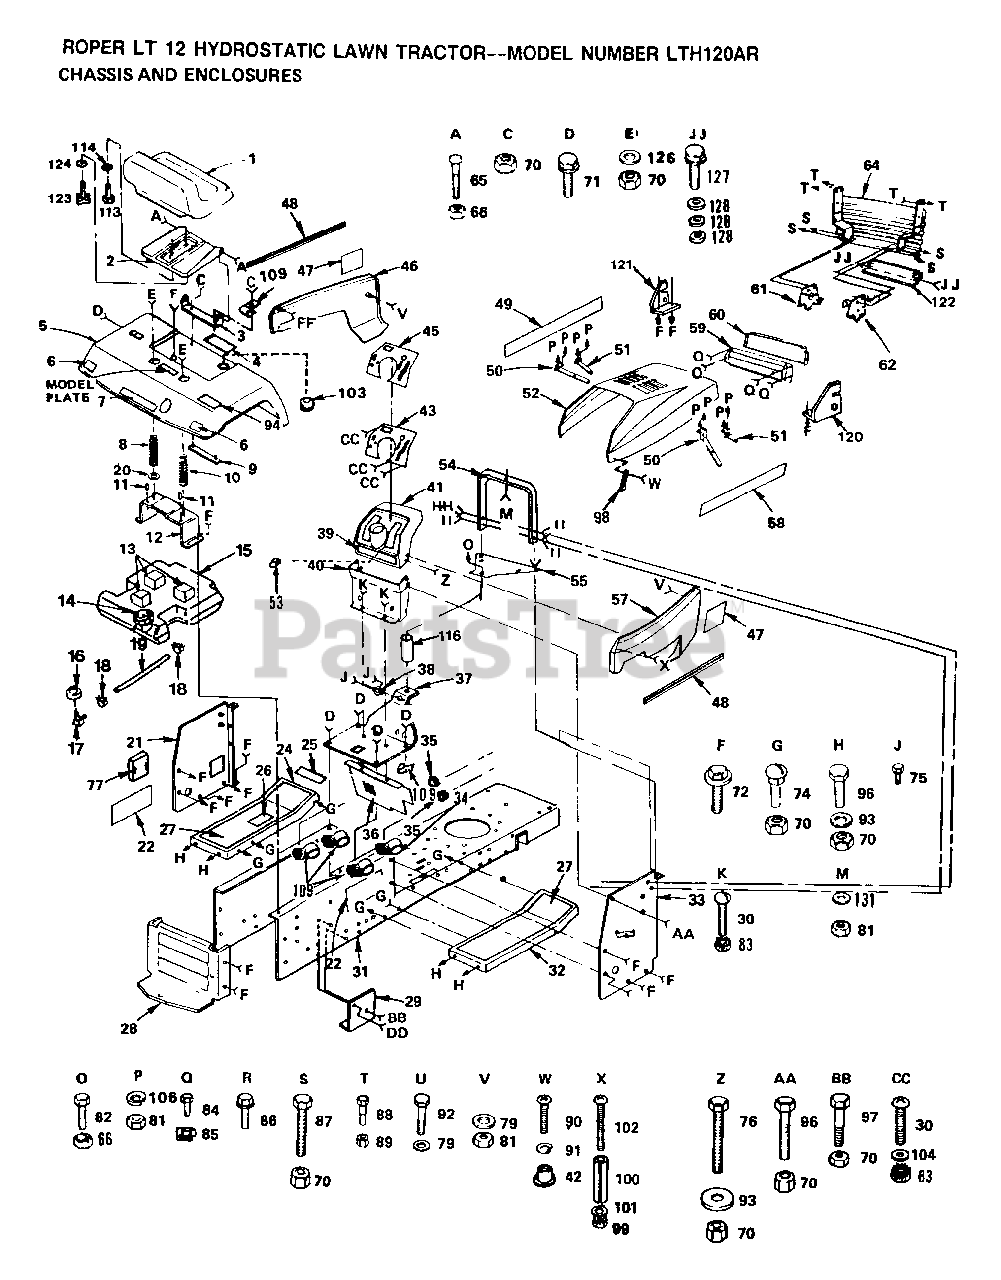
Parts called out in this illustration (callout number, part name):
6	REFLECTOR-TAIL YT
11	NUT-PUSH YT
13	PAD-SPACER T
16	BUSHING OUTLET T
17	FUEL TANK STEM GT
20	SHIM WASHER T
21	DASH PANEL T
29	DEFLECTOR HYT
30	SCREW
34	INSUL CLIP T
40	LOWER DASH
42	WELDNUT
43	PLATE - DASH
45	DECAL - DASH
53	PLUG BUTTON T
60	LENS LT
61	SUPPORT LH YTH
62	SUPPORT RH YTH
71	SCREW LT
72	SCREW
74	BOLT
76	BOLT
79	WASHER PM
82	BOLT
85	"""J"" FASTENER LT"
86	SCREW
88	BOLT T
90	SCREW
91	LOCKWASHER
92	SCREW HEX CRT
93	WASHER
94	DECAL-CAUTION
98	HOOD LATCH T
100	SPACER LT
101	WASHER
102	SCREW
103	GROMMET T
104	WASHER
109	CLIP T
113	BOLT T
116	SPACER-SPLIT YTV
120	SUPPORT RH YTH
121	SUPPORT LH YTH
123	"KNOB 1/2"" YT"
124	WASHER
126	WASHER
127	SCREW
128	WASHER PM
